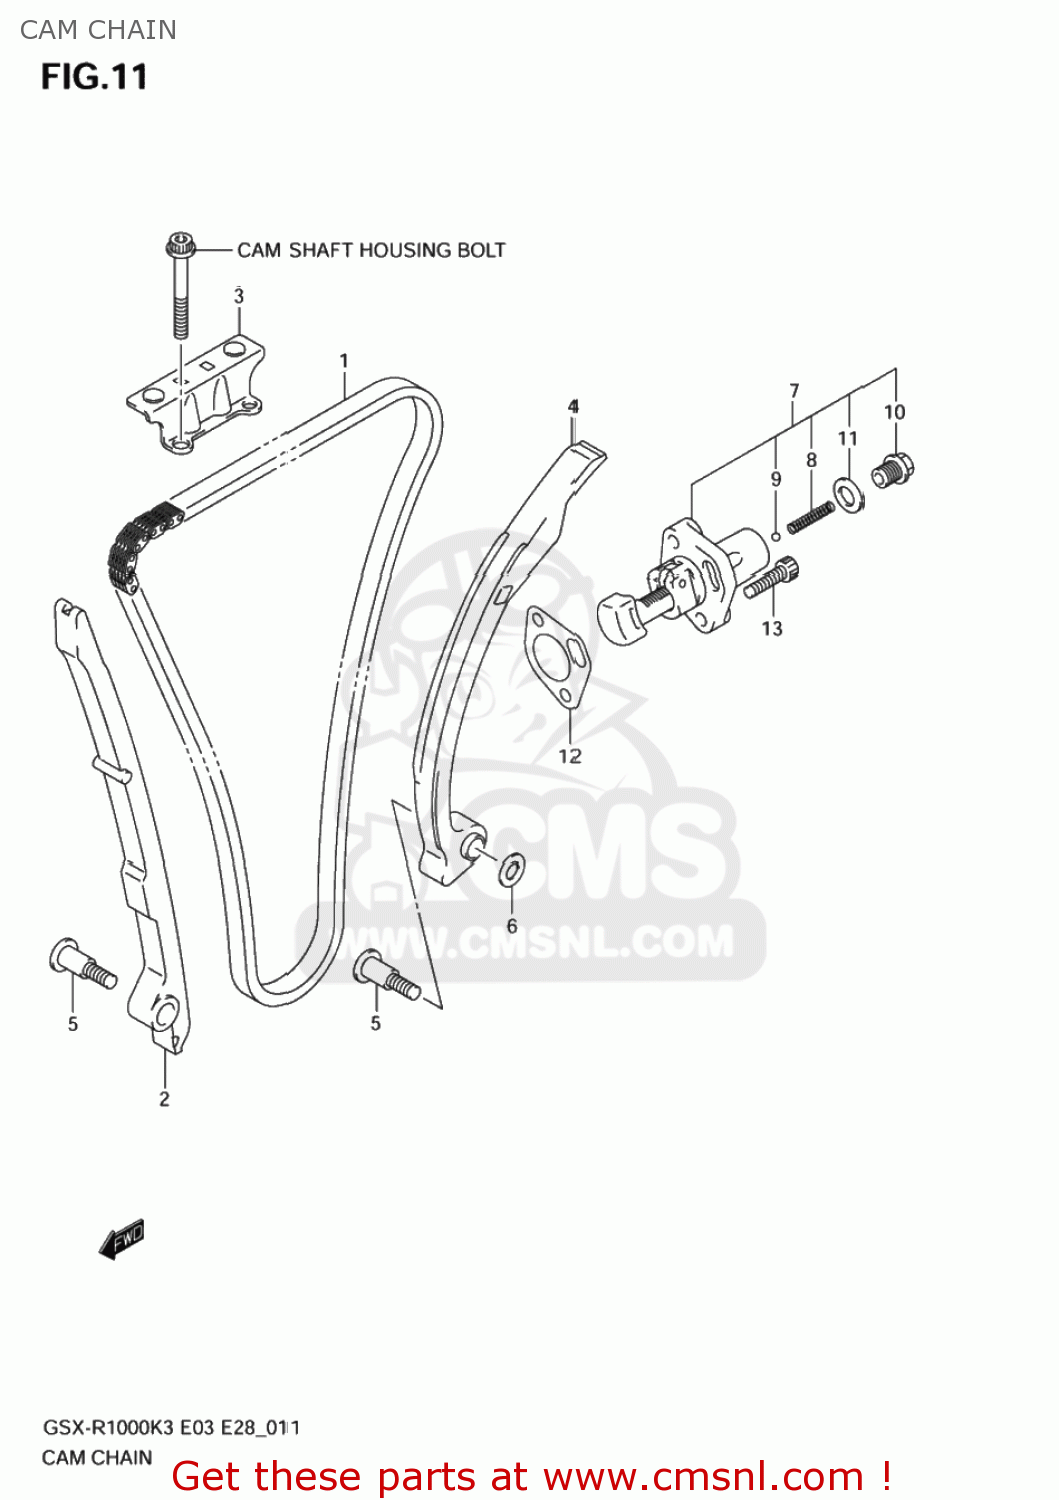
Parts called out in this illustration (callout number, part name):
1	CHAIN COMP,CAM
2	GUIDE,CAM CHAI
3	GUIDE CAM CHAIN NO,2
4	TENSIONER,CAM CHAIN
5	BOLT,CAM CHAIN TENSIONER/GUIDE
6	WASHER,CAM CHAIN TNSN
7	ADJUSTER ASSY,
8	SPRING
9	BALL
10	PLUG,FR TENSIONER ADJ
11	GASKET,TENSIONER ADJUSTER (NAS)
12	GASKET,TENSIONER ADJUSTER (NAS)
13	BOLT,CL.COVER
